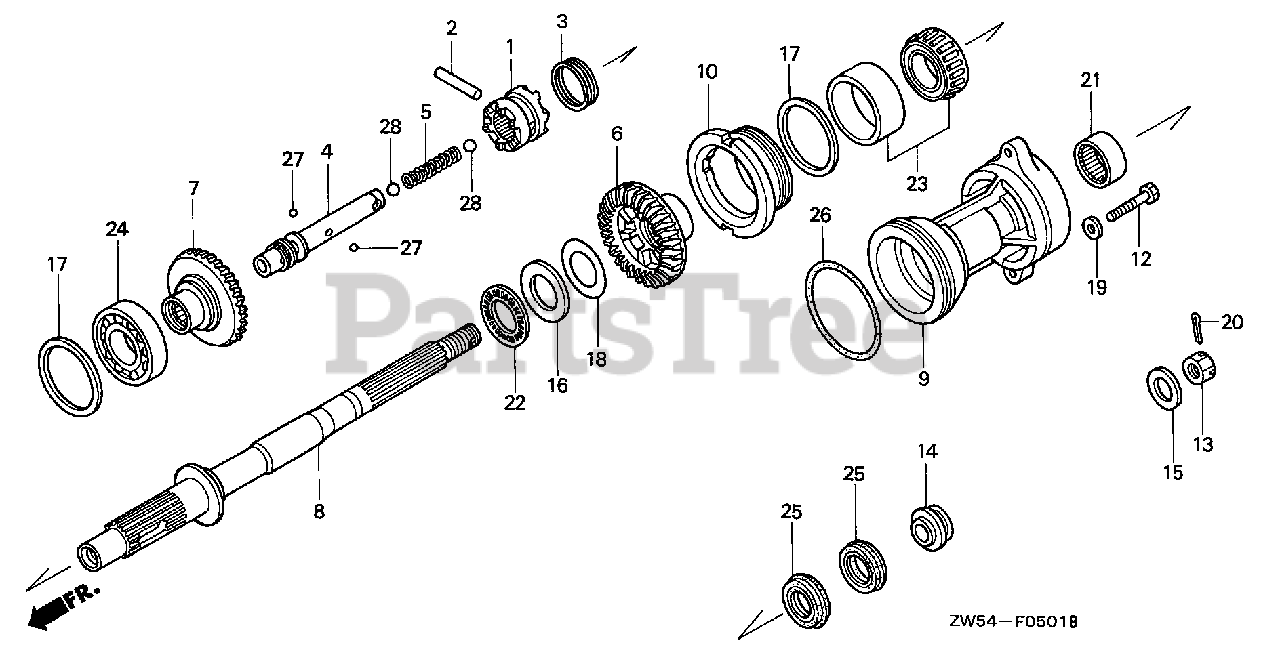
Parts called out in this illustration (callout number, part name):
1	SHIFTER, CLUTCH
2	PIN, SHIFTER (8X47)
3	RING, CROSS PIN
4	SLIDER, SHIFT
5	SPRING, SHIFT
6	GEAR, BEVEL (F)(COUNTER ROTATION)
7	GEAR, BEVEL (R)(COUNTER ROTATION)
8	SHAFT, PROPELLER (COUNTER ROTATION)
9	HOLDER, PROPELLER SHAFT *NH282MU* (COUNTER ROTATION) (OYSTER SILVER METALLIC-U)
10	HOLDER, BEARING
12	BOLT, HEX. (10X40)
13	NUT, CASTLE (18MM)
14	WASHER, PROPELLER THRUST
15	WASHER, PLAIN (18.5MM)
16	WASHER, THRUST BEARING
17	SHIM A, BEVEL (0.10) (FR)
17	SHIM B, BEVEL (0.15) (FR)
17	SHIM C, BEVEL (0.30) (FR)
17	SHIM D, BEVEL (0.50) (FR)
18	SHIM A, THRUST (0.10)
18	SHIM B, THRUST (0.15)
18	SHIM C, THRUST (0.30)
18	SHIM D, THRUST (0.50)
19	WASHER, PLAIN (10MM)
20	PIN, SPLIT (4.0)
21	BEARING, NEEDLE (30X37X26)
22	BEARING, THRUST (F)
23	BEARING, TAPERED (50X82X21.5)
24	BEARING, RADIAL BALL (40X82X18)
25	SEAL, WATER (30X45X7)
26	O-RING (94X4.1)
27	BALL, STEEL (#6) (3/16)
28	BALL, STEEL (#11) (11/32)
